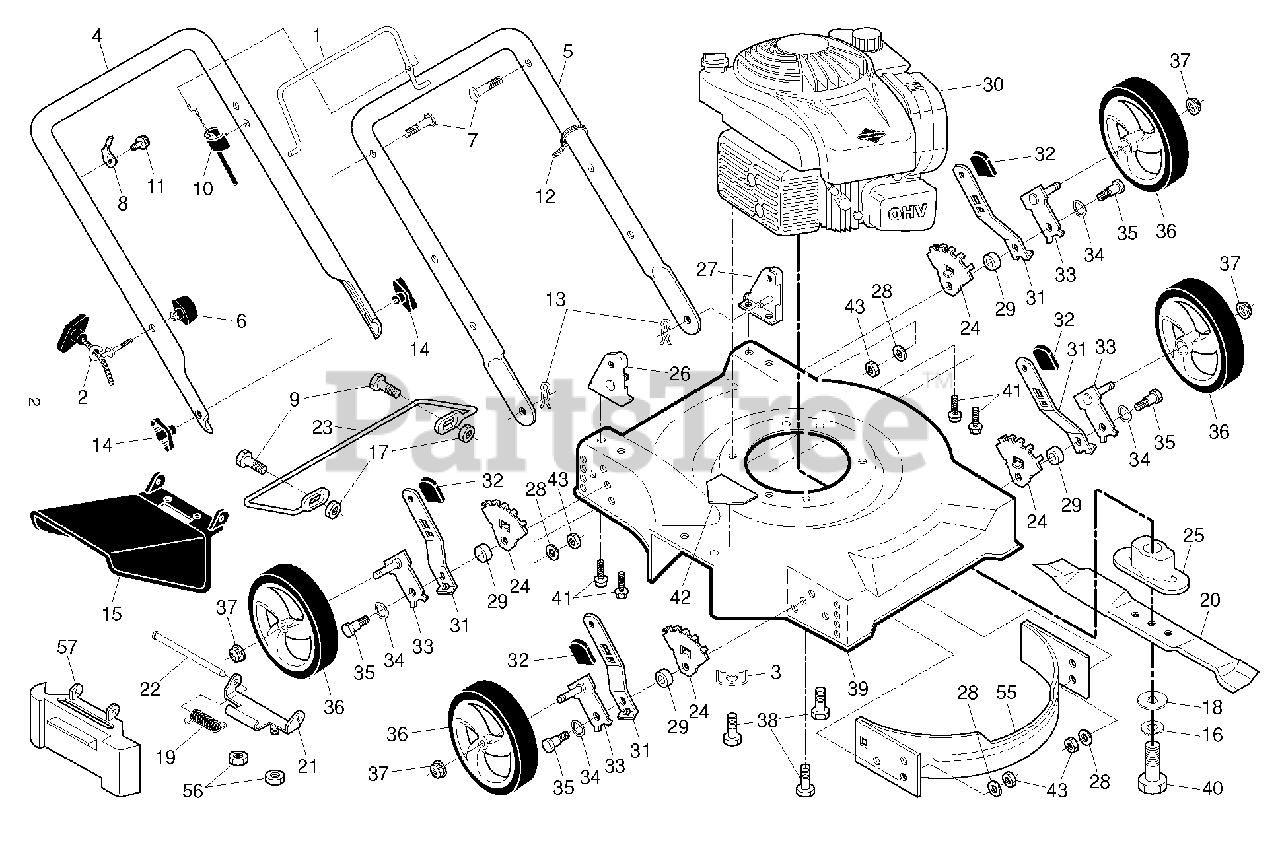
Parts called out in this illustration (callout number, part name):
1	BAIL.CONT.D.STRAIGHT.PUSH.BLK
2	Rope Guide, Blk Zinc Chrom
4	HANDLE.UPPER.ECONOMY.BLACK
5	HANDLE.LOWER.D-STRAIT.BLACK
6	T-Knob, New Rope Guide
7	BOLT, HANDLE 5/16-18X1.75
8	BRACKET.UPSTOP.RT
10	CABLE.MZR.RATO.22"LOW.
12	TIE GUIDE
13	HAIRPIN COTTER
14	KNOB, DEFLECTOR
16	LOCKWASHER
18	WASHER,HARDEN
20	BLADE.20.MULCH.(50DK,6020MD)
21	HINGE DEFLECTOR
22	HINGE ROD
24	WHEEL ADJ BRACKET FRONT
25	Blade Adapter, 7/8
26	HANDLE BRACKET ASM. RH
27	HANDLE BRACKET ASM. LH
28	WASHER
29	SPACER.HEIGHT.ADJUSTER
31	SELECTOR SPRING, FRONT
33	AXLE ARM ASSY.
34	WASHER FLAT
35	SHOULDER BOLT 5/16-18
37	NUT.HEX.FLANGE.3/8-16.LOCKNUT
38	BOLT 3/8-16X1-1/8
39	KIT.HSG.20.SD.PU.W/HB.MS667.CE
40	SCREW, HEX HD 3/8-24 X 1-3/8
41	SCREW 5/16-18
42	DECAL.INTERNATIONL.CUTFINGER
43	NUT.71038.31-18.HEX.NYLOCK
56	LOCKNUT
